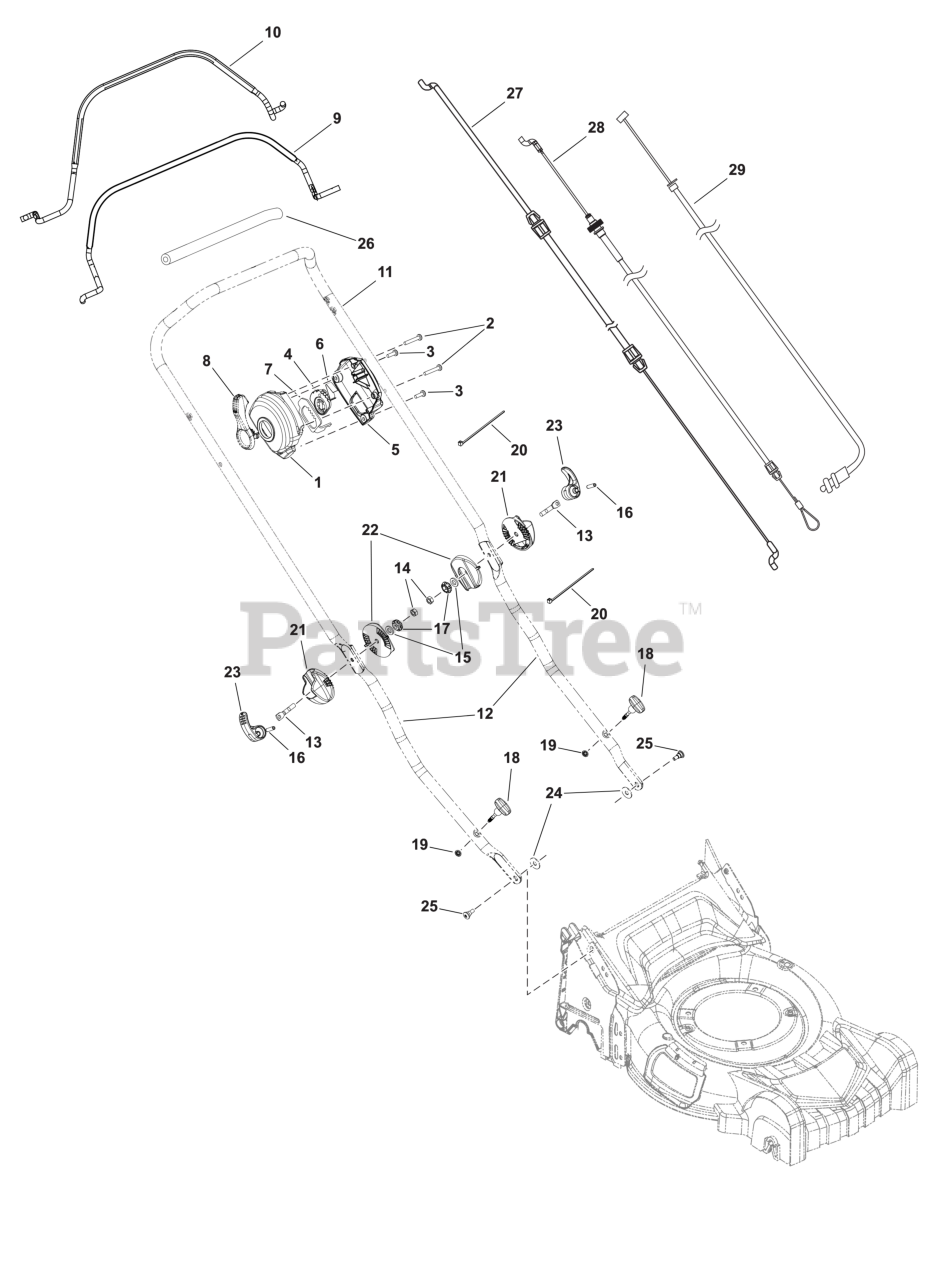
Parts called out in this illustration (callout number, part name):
3	NUT, Nylock, M6
4	CABLE CLIP
5	WASHER, A6.4
8	BOLT, Eye
9	HANDLE, Upper
10	SUPPORT, Handle
12	BOLT, Wing
13	BAIL, Control, Red
14	BAIL, Drive
15	CABLE, Drive
16	CABLE, Control
17	CABLE, Speed Select
18	CONTROL HOUSING, Upper
21	SPEED ACTUATOR
22	CONTROL HOUSING, Lower
23	SPRING, Shift
24	RACK PLATE
25	LEVER, Speed Select
31	PIN, Spring
32	BOLT, Eye
33	SUPPORT, Handle, Outer
34	SUPPORT, Handle, Inner
